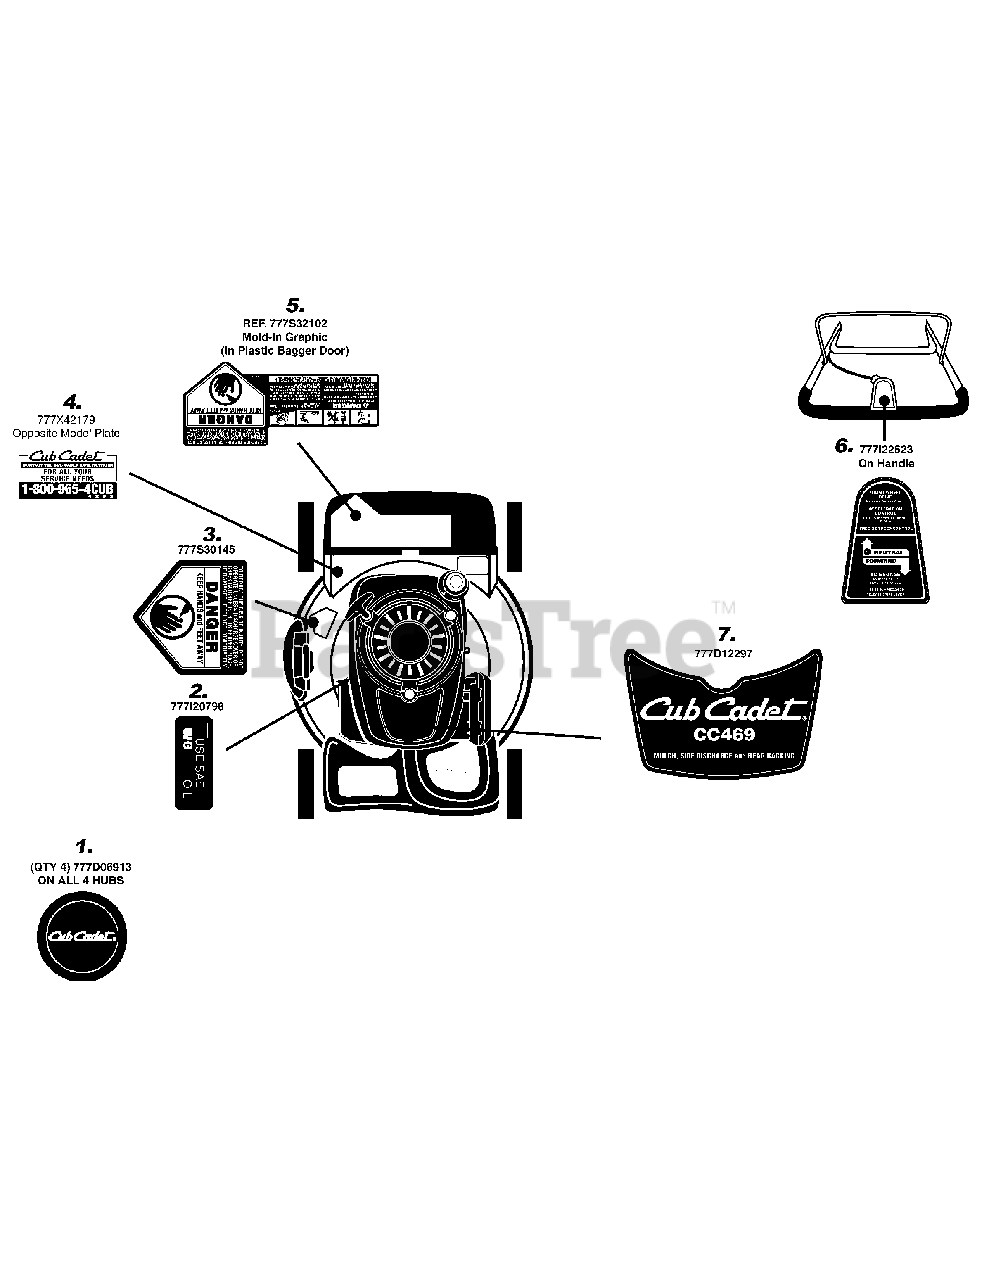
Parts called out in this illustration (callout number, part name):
1	LABEL-HUB CAP
2	LABEL-SHROUD
3	LABEL
4	LABEL-CUB HOTLINE
6	LABEL-FRNT WHEEL CONTROL LEVER
7	LABEL-CC469 SHROUD
